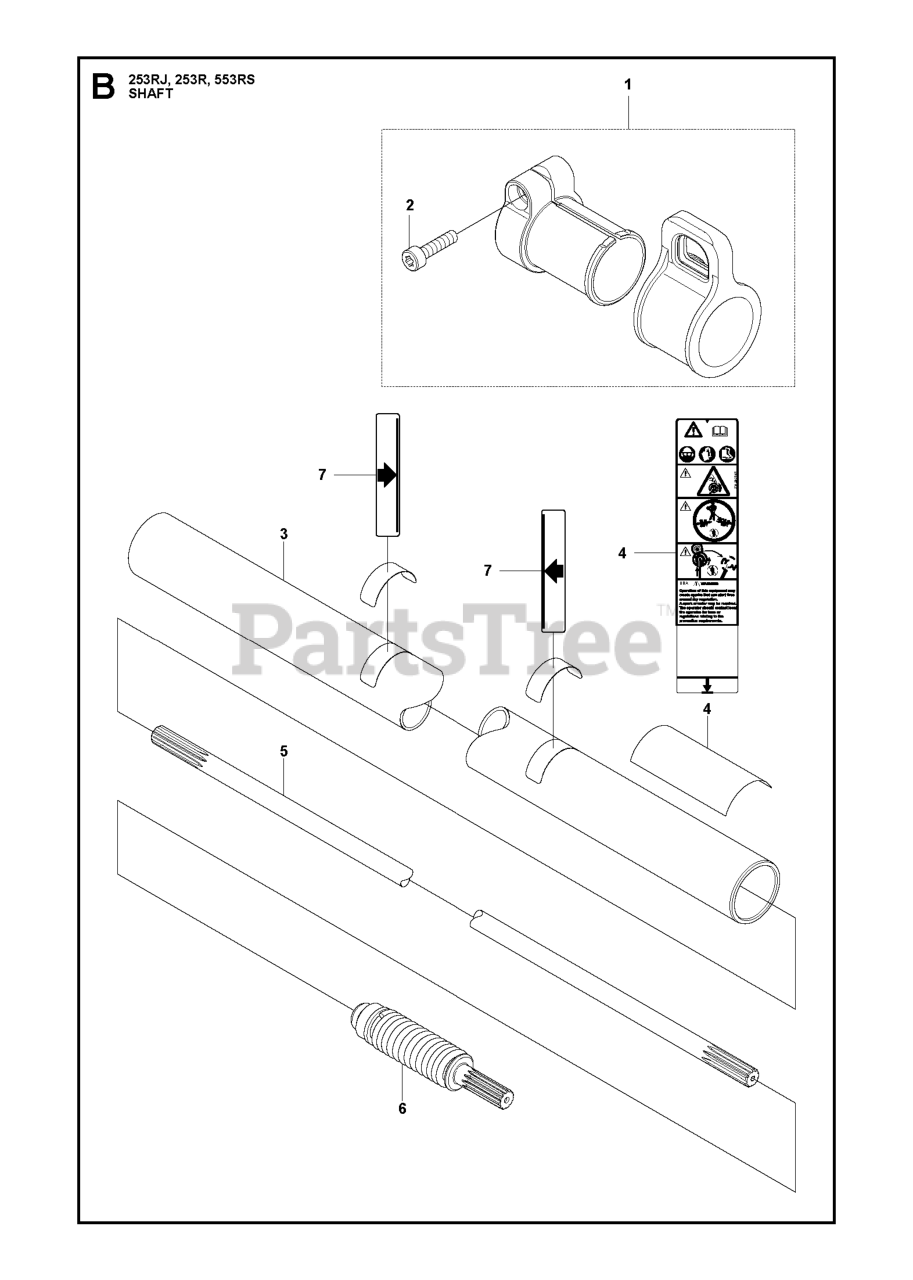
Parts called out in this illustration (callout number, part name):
1	HANGER ASSY.
2	BOLT
4	LABEL WARNING TRIMMERS AND BRU
